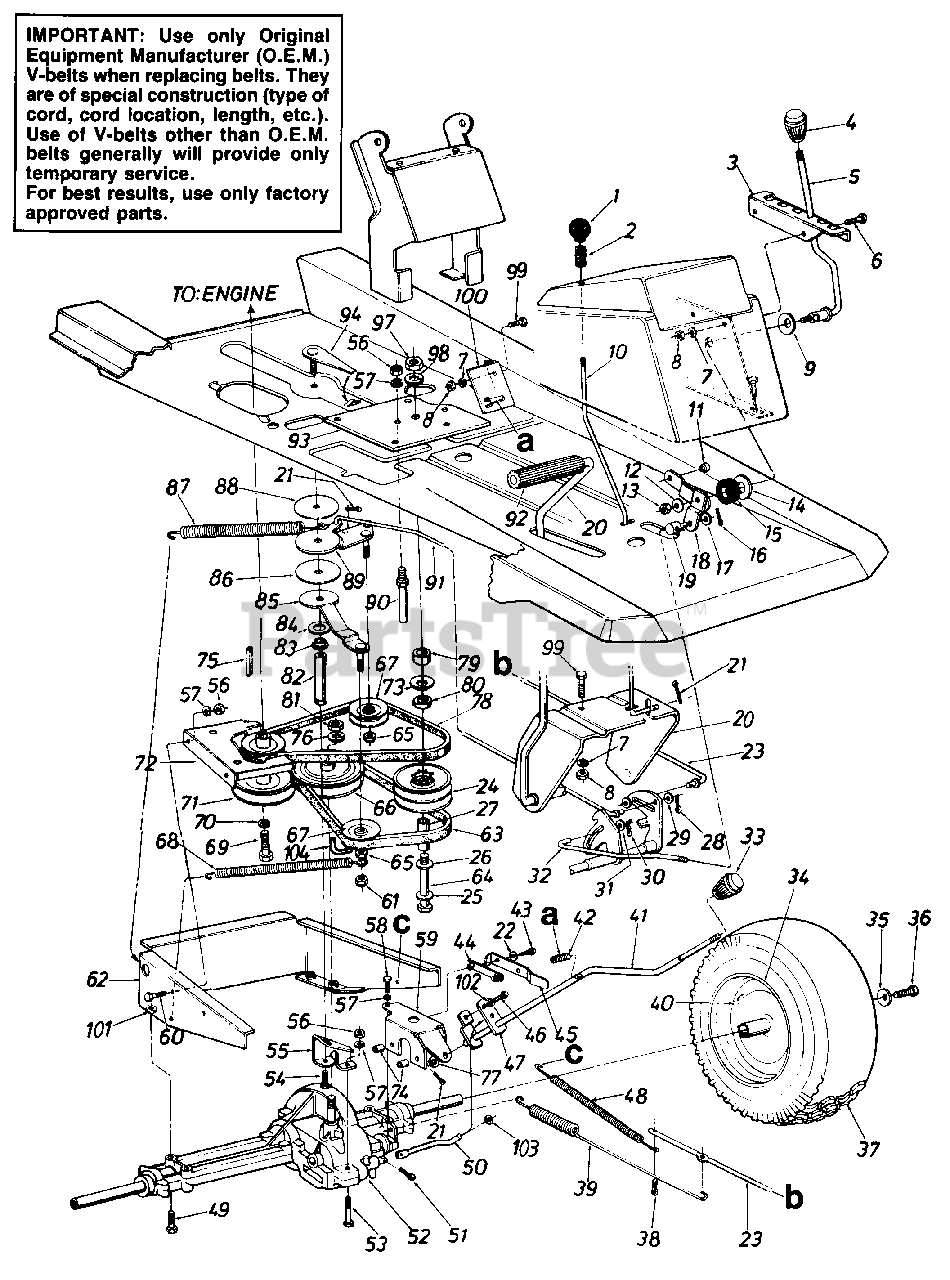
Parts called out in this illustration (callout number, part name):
1	Ball Knob 1/4-20 Thd. 1.25"
2	Compression Spring
5	Speed Control Lever
6	Truss Mach. Scr. 5/16-18 x .75" Lg.
7	L-Wash. 5/16" I.D.
8	Hex Nut 5/16-18 Thd.
9	Bell-Wash. .345" I.D. x .88"
10	Brake Locking Rod
12	Bell-Wash. .345" I.D. x .08"
13	Hex Cent. L-Nut 5/16-18 Thd.
14	Fl-Wash. .50" I.D. x 1.5" O.D.
15	Rubber Washer
16	Intern. Cotter Pin 1/2" Dia.
17	Fl-Wash. .34" I.D. x .68" O.D.
18	Speed Control Lever Brkt. Ass'y.
19	Ferrule Engagement
20	Clutch/Brake Pedal Ass'y.
21	Cotter Pin 3/32" Dia. x .75"
22	Plastic Washer
23	Brake Rod
24	Variable Speed Pulley Ass'y.
25	Fl-Wash. .4" I.D. x 1.25" O.D.
26	Thrust Brg. 1.25" O.D. x .56" I.D.
27	Spacer Sleeve 2.71 "
28	Cotter Pin 1/8" Dia. x 1.25"
29	Fl-Wash. .34" I.D. x .60" O.D.
30	Intern. Cot-Pin 5/16" Dia.
31	Fl-Wash. .34" I.D. x .60" O.D.
32	Speed Control Rod
33	Shift Knob
35	Bell-Wash. .345" I.D. x.88"
36	Hex L-Bolt 5/16-24 x .75" Lg.
38	Cotter Pin 1/8" Dia. x 1.25
39	Extension Spring 17.0" Lg.
40	Air Valve
43	Hex Wash. Hd. Scr. #8 x .5" Lg
44	Insulator Nut
45	Spring Switch
46	Hex Bolt 1/4-20 x .50" Lg.
47	Shift Lever Adjusting Link
48	Ext. Spring 81/4" Lg.
49	Hex Bolt 5/16-18 x 2.5" Lg.
50	Shift Rod
51	Intern. Cotter Pin
52	Transaxle
53	Hex Bolt 1/4-20 x 1.75" Lg.
54	Hex Bolt 3/8-24 x .75" Lg.
57	L-Wash. 1/4" I.D.
58	Self-Tap Mach. Scr. Type "C" 1/4-20 x 1.37" Lg.
59	Shift Lever Support Brkt.
60	Hex Bolt 1/4-20 x 1.00" Lg.
61	Hex L-Nut 3/8-24 Thd.
64	Hex Bolt 3/8-16 x 4.5" Lg.
65	Hex Ins. L-Nut 3/8-24 Thd.
66	5/8 V-Pulley .500" I.D. x 6"
67	V-Belt Idler .38" I.D. x 3.06"
68	Ext. Spring .50" O.D. x 6.37"
69	Hex Bolt 7/16-20 x 1.00" Lg.
70	L-Wash. 7/16" I.D.
71	Engine Pulley .500" O.D. & 3.56" O.D.
72	Upper Eng. Belt Guard
73	Bell-Wash. .4" I.D. x 1.12" O.D.
74	Spacer.256" I.D. x .50" O.D.
75	Sq.-Key 1/4" X 2.00" Lg.
76	L-Wash. 1/2" I.D.
77	Fl-Wash. .469" I.D. x .88" O.D.
78	V-Belt
79	Spacer 1.00" x .380" O.D.
80	Thrust Wash. .56" I.D. x 1.25" O.D.
81	Hex Nut 1/2-13 Thd.
82	Torque Rod
83	Flange Bearing .378
84	Fl-Wash. .640" I.D. x 1.24"
85	Idler Bracket Ass'y.
86	Thrust Wash. .635" I.D.
87	Extension Spring 7.58" Lg.
88	Thrust Wash. .385" I.D.
89	Idler Bracket Ass'y. For Clutch
90	Belt Guard Pin 1/4" Dia.
91	Clutch Rod
92	Foot Pad
93	Mtg. Brkt. Variable Pulley
98	L-Wash. 3/8 Heavy Duty
99	Hex Bolt 5/16-18 x .75" Lg.
100	Shift Lever Spring Brkt.
101	Hex Sems Nut 5/16-18 Thd.
102	Bell-Wash. .265" I.D. x .75" O.D.
103	Push On Retaining Ring
104	Belt Guard
